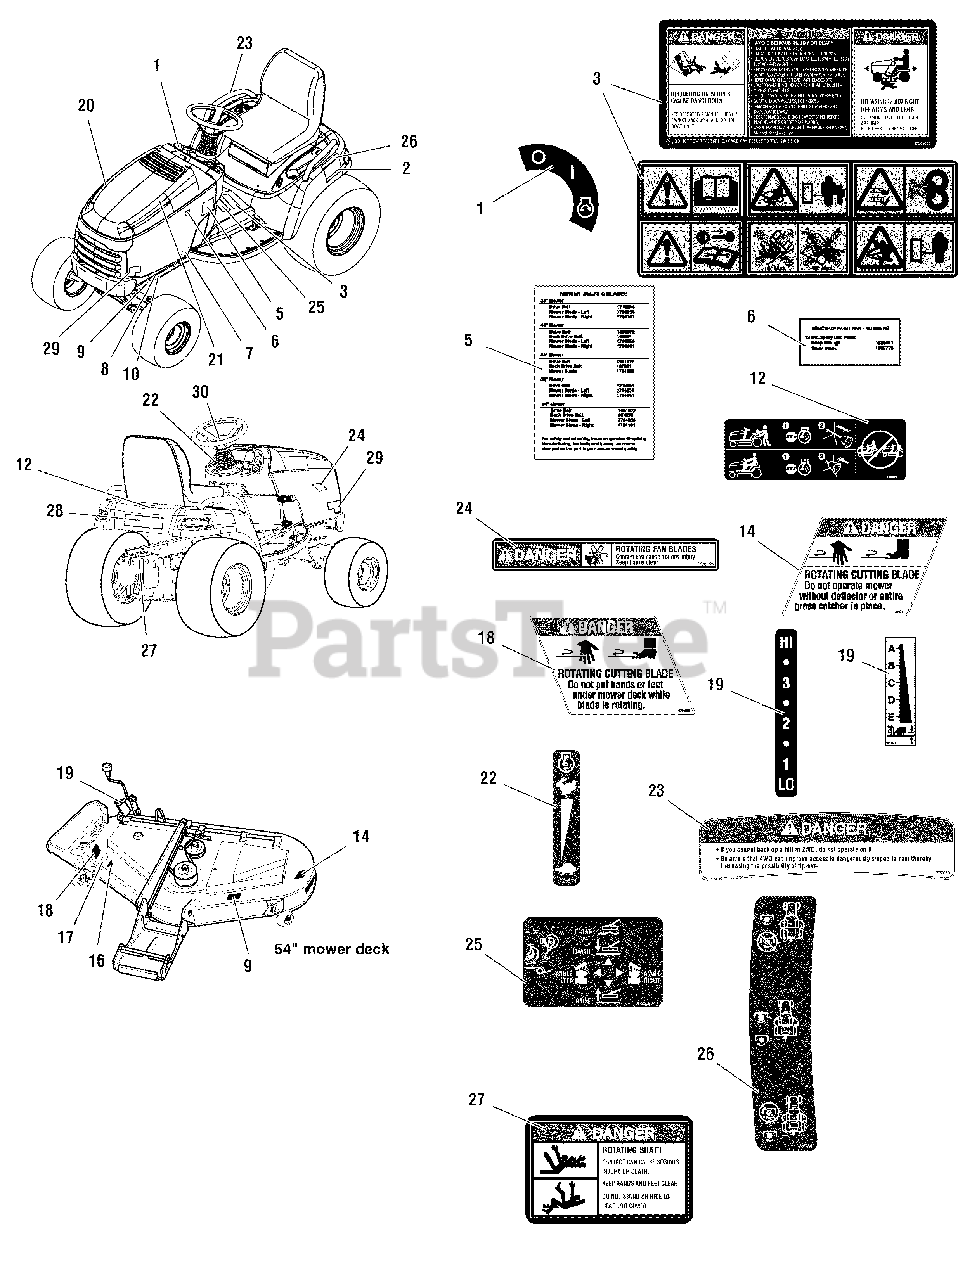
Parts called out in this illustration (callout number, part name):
1	DECAL, Ignition Switch Symbols, White/Black
2	DECAL, Automatic Control Traction
3	DECAL, Tunnel Cover, Danger Slopes/Blades
3	DECAL, Tunnel Cover
5	DECAL, Drive Belts, Mower Blades
6	DECAL, Touch Up Paint, Orange, Black, Red
7	DECAL, Protective Sticker
8	* LABEL, Decibel, Power Mass
9	* DECAL, I.D. Plate
10	* DECAL, Patent
12	DECAL, Transmission Release Valve
14	DECAL, Danger Do Not Put Hands/Feet in Mower
16	* DECAL, OPEI Certified
17	DECAL, 54", Silver on Black with Stripe
18	DECAL, Danger Do Not Operate without Deflector
19	DECAL, Height of Cut
20	DECAL, Snapper, 4WD Diesel, R.H.
21	DECAL, Snapper, 4WD Diesel, L.H.
22	DECAL, Throttle Speed Silver/Black
23	DECAL, Danger 4WD Tip Over On Slopes
24	DECAL, Rotating Fan Blades
25	DECAL, Hydraulic Lift
26	DECAL, PTO Selector Position
27	DECAL, Danger, Rotating Parts
27	DECAL, Danger, Rotating Parts Icons (Similar)
28	DECAL, Snapper, Silver/Black
29	DECAL, GT600 27HP Snapper
30	DECAL, Snapper Steering Wheel Icon
